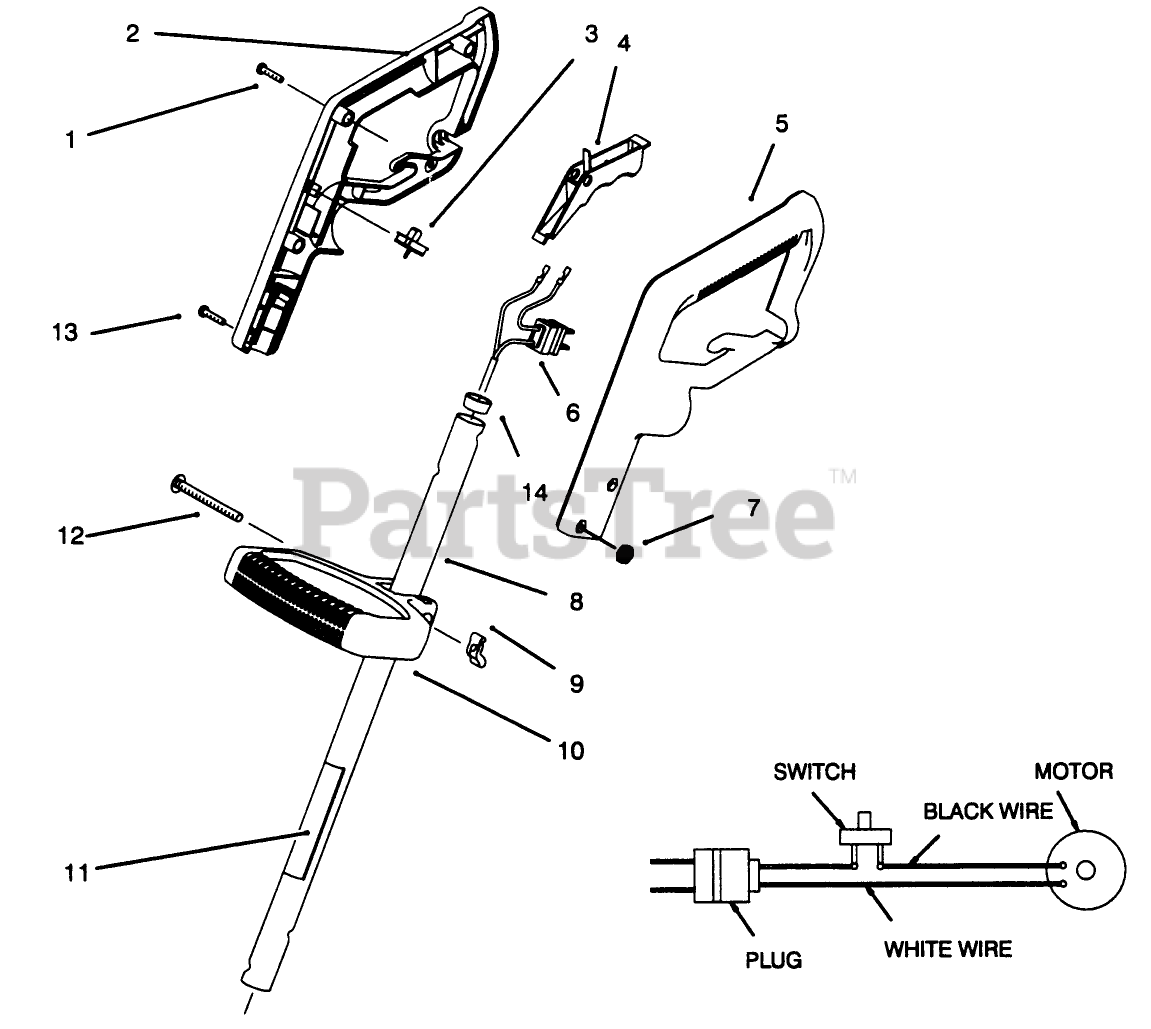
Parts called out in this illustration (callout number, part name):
1	Screw
2	HAND GRIP R.H.
3	SWITCH
4	TRIGGER
5	HAND GRIP L.H.
6	WIRING HARNESS
7	NUT-HEX
8	Tube Assembly (Incl. Ref. #11)
9	1/4"-20 STAMP WNG NUT
10	MID HANDLE
11	Decal-Safety
12	SCREW-CARR.25-20 X 2.50
13	SCREW-PPH
14	1200PC-TUBE BUSHING
